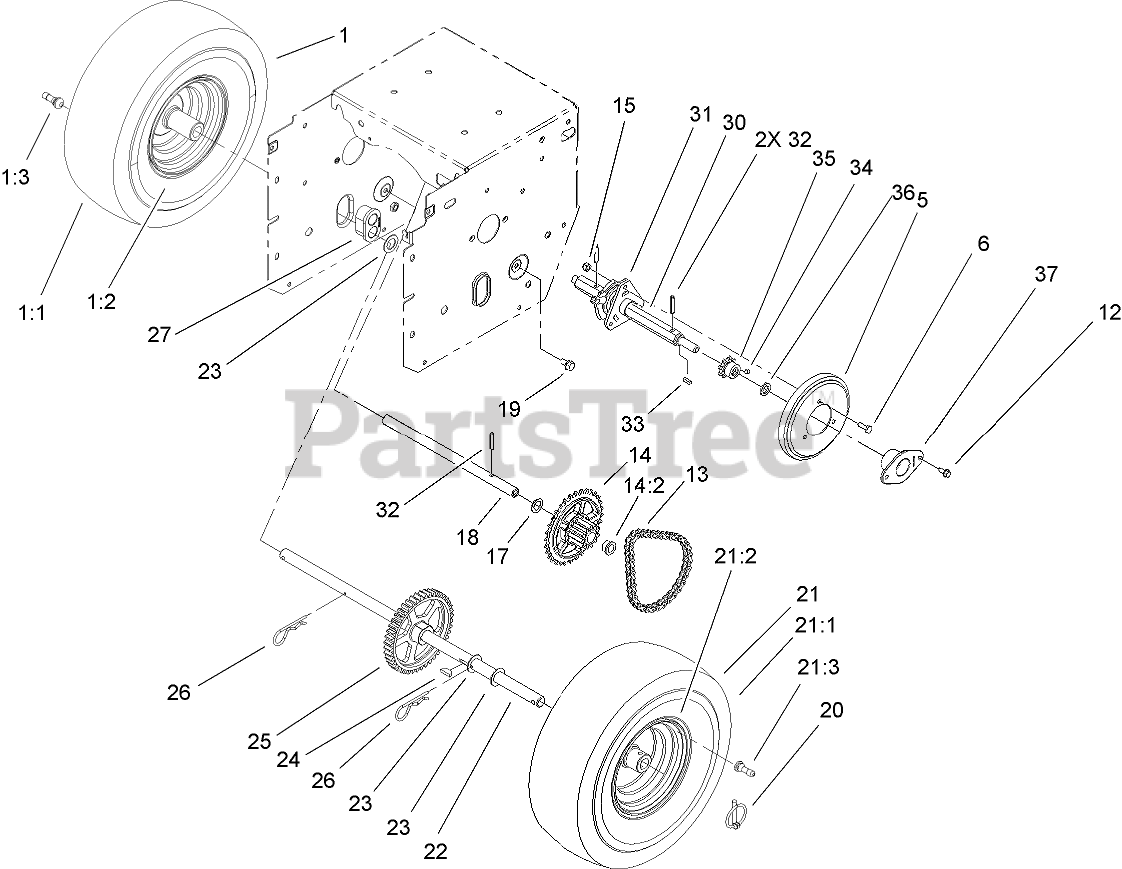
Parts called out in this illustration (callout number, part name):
1	RH WHEEL AND TIRE ASM
1:2	RIM-TIRE
1:3	STEM-VALVE
5	WHEEL-FRICTION
6	SCREW-HH
12	SCREW-HWH
13	CHAIN-ROLLER
13	LINK-CONNECTING
14	SPROCKET ASM
14:2	BUSHING-FLANGE
15	NUT-LOCK, NI
17	WASHER-FLAT
18	SHAFT-INTERMEDIATE
19	SCREW-HWHTF
20	KLIK PIN ASM
21	LH WHEEL AND TIRE ASM
21:2	RIM-TIRE
21:3	STEM-VALVE
22	SHAFT-AXLE
23	WASHER-THRUST
24	KEY-WOODRUFF
25	GEAR-AXLE, 44 TOOTH
26	PIN-HAIR
27	BEARING-AXLE
30	SHAFT-HEX
31	TRUNNION-HEX
32	PIN-ROLL, SLOTTED
33	KEY-SQUARE
34	SCREW-HSH
35	SPROCKET-8 TOOTH
36	SPACER-BUSHING
37	RETAINER-BEARING
